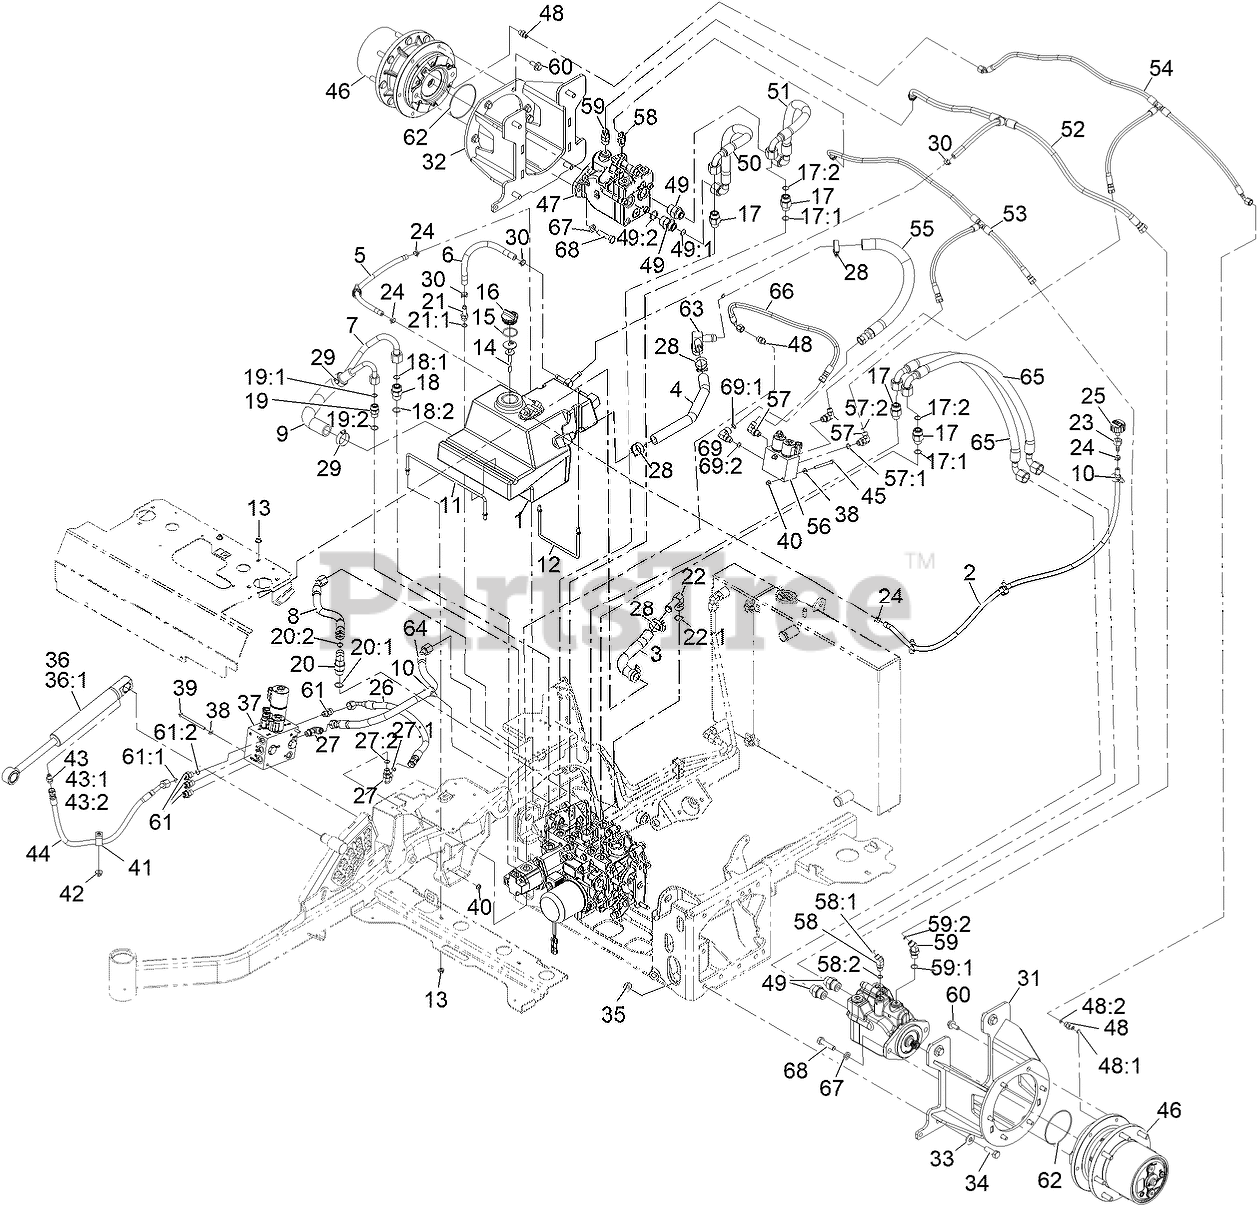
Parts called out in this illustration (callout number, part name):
1	HYD RESERVOIR ASM
3	HOSE-RETURN
4	HOSE-RETURN
7	TUBE ASM
8	HOSE ASM-HYD HP
9	HOSE-SUCTION
10	CLIP-TIE
11	ROD-SUPPORT, HYD TANK
12	ROD-SUPPORT, HYD TANK
13	NUT-HF, NI
14	DIPSTICK
16	PLUG-PLASTIC
17	FITTING-STRAIGHT
17:1	O-RING
18	FITTING-STRAIGHT
18:1	O-RING
18:2	O-RING
19	FITTING-STRAIGHT
19:1	O-RING
19:2	O-RING
20	FITTING-ELBOW, 90 DEG
20:1	O-RING
20:2	O-RING
21	ADAPTER-STRAIGHT
21:1	O-RING
22	FITTING-90
22:1	O-RING
23	FITTING-STRAIGHT
24	CLAMP-HOSE
25	BREATHER
26	HOSE ASM
27	FITTING-ELBOW, 90 DEG
27:1	O-RING
27:2	O-RING
28	CLAMP-HOSE
29	CLAMP-HOSE
30	CLAMP-HOSE
31	MOTOR MOUNT, R [BLACK]
32	WASHER-SPRING DISC 1/2
33	WASHER-SPRING
34	SCREW-HH
35	NUT-HHF
36	CYLINDER-LIFT
36:1	CYL Repair Kit
37	VALVE ASM-LIFT AND FOLD
38	WASHER-FLAT
39	SCREW-HH
41	CLIP-LOOM
42	NUT-HF, NI
43	FITTING-HYD, STRAIGHT
43:1	O-RING
43:2	O-RING
44	HOSE ASM
45	SCREW-HH
46	PLANETARY ASM-11.96:1
47	MOTOR-HYD, PISTON, 30CC
48	FITTING-STRAIGHT
48:1	O-RING
48:2	O-RING
49	FITTING-STRAIGHT
49:1	O-RING
49:2	O-RING
50	HOSE-HP
51	HOSE-HP
52	HOSE ASM-HYDLPTEE
53	HOSE ASM-HYD HP TEE
54	HOSE ASM-HYD HP TEE
55	HOSE ASM-HYDLP
56	VALVE-HYD, BRK-2SPD
57	FITTING-ELBOW, 90 DEG
57:1	O-RING
57:2	O-RING
58	FITTING
58:1	O-RING
58:2	O-RING
59	FITTING-HYD, 45 DEG
59:1	O-RING
59:2	O-RING
60	SCREW-HHF
61	FITTING-STRAIGHT
61:1	O-RING
61:2	O-RING
64	HOSE ASM-HYD HP
65	HOSE-HP
66	HOSE ASM-HYD HP
68	SCREW-HH
69	Fitting-HYD, 90 DEG
69:1	O-RING
69:2	O-RING
